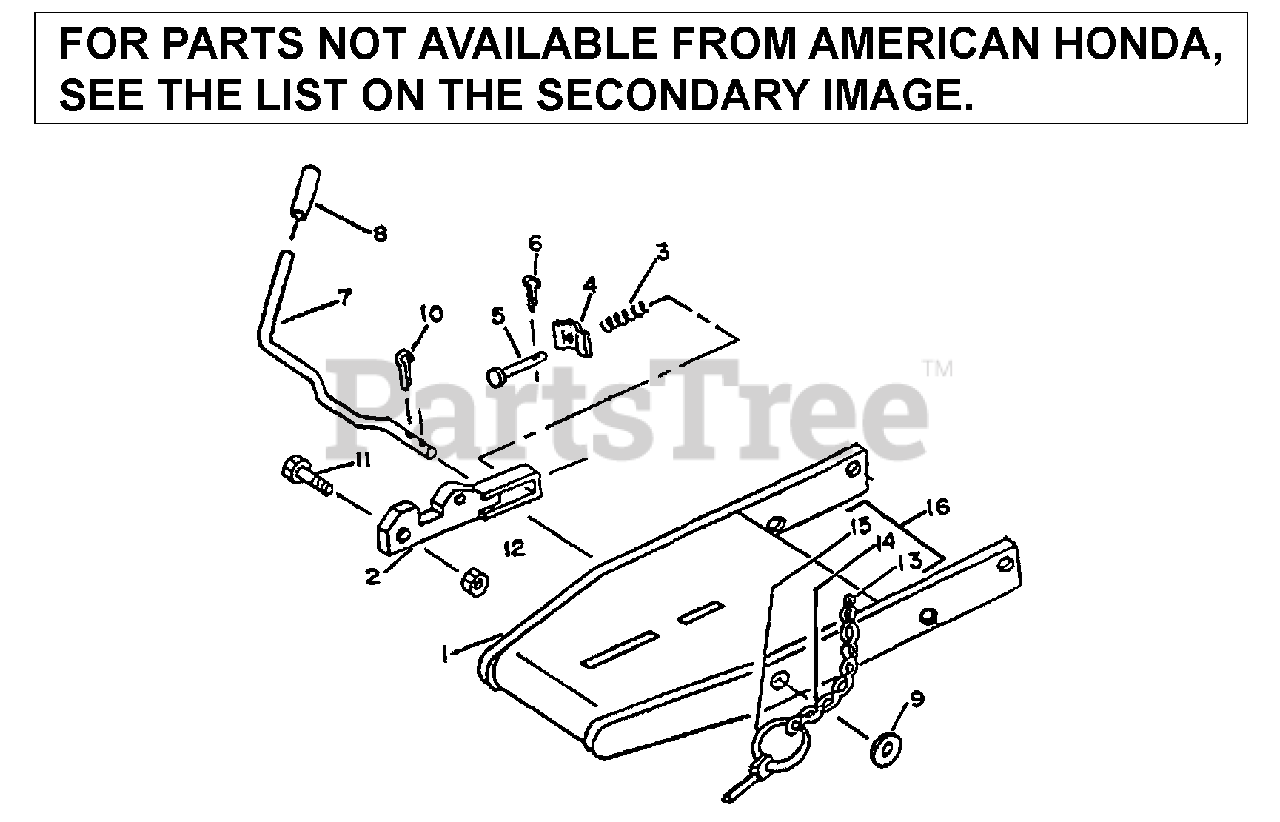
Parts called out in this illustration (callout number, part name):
2	LATCH, MALE HITCH
4	PLATE, SPRING
5	PIN (1/4X1-3/4")
7	LEVER, ATTACHING
16	LATCH, QUICK HITCH
